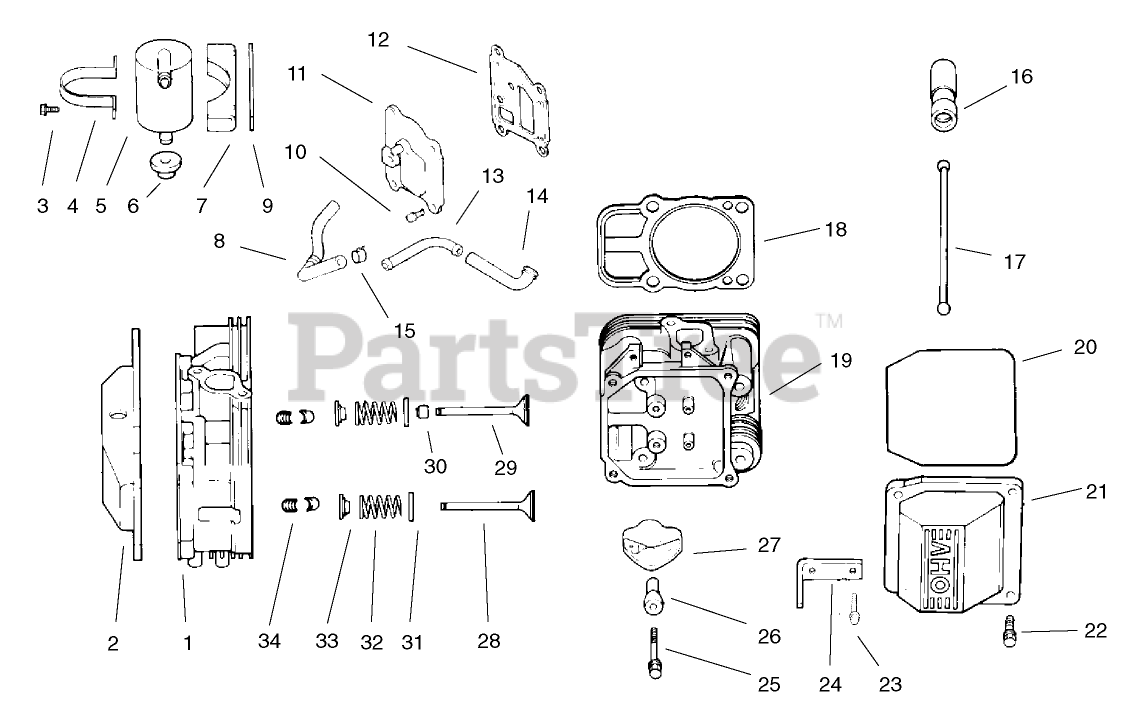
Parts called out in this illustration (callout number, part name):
1	Head ASM-#1 Cylinder (Only On: 72103, 72083)
2	Kit-Valve Incl 6 20-22
3	Screw M5x0.8x16 (Only On: 72042, 72063, 72062, 72043)
4	Strap-Lifting
5	Kit-Breather Incl 3-9
6	Grommet-Rubber (Only On: 72103)
7	Bracket
8	Hose-Breather
9	Spacer
10	Screw
11	Cover-Breather (Only On: 72103)
12	Gasket-Breather
13	Fitting
14	Hose-Breather
15	Clamp
16	Lifter-Valve
17	Rod-Push
18	Gasket-Cylinder Head
19	Head ASM-#2 Cylinder (Only On: 72103, 72083)
20	O-Ring
21	Kit-Valve Cover (Incl. Ref. #2 3)
22	Screw-Shoulder
23	Screw
24	Strap-Lifting
25	Screw
26	Pivot-Arm, Rocker
27	Arm-Rocker
28	Valve-Exhaust
28	Valve-Exhaust (.25)
29	Valve-Intake
29	Valve-Intake (.25)
30	Seal-Valve Stem
31	Retainer-Spring
32	Spring-Valve
33	Cap-Valve Spring
34	Kit-Retainer
